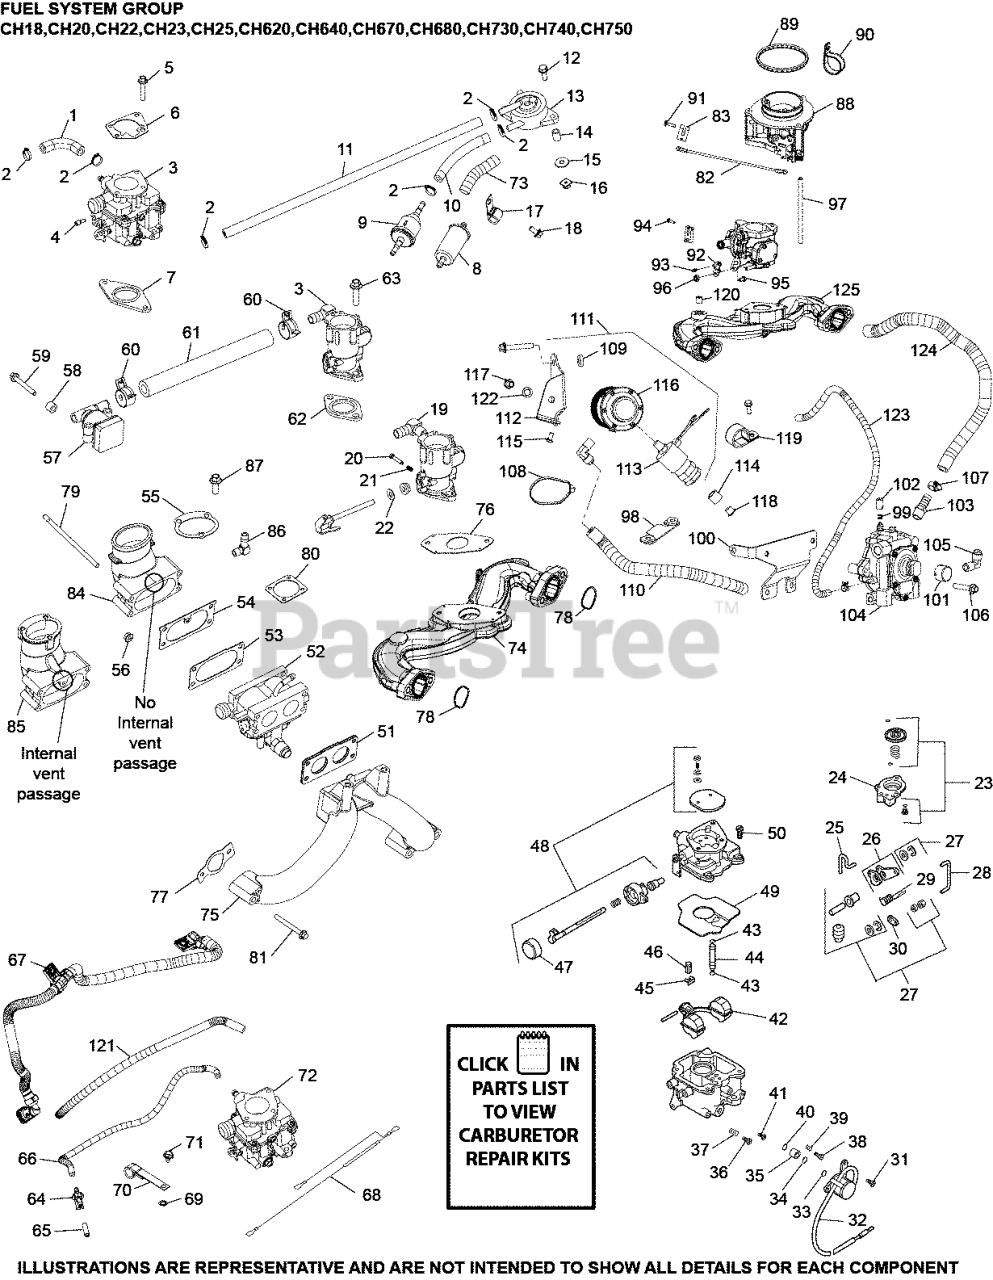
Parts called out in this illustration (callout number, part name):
1	HOSE,LW PERM.FUEL 24.00"-USE 25 111 81-S
2	CLAMP, HOSE (KM)-USE 25 237 31-S
3	KIT,CARB (KEIHIN) W/GASKETS-(#24853310S)
5	SCREW, FLG M6X1.0X25
6	GASKET, AIR CLEANER BASE
7	GASKET, CARBURETOR
9	FILTER, FUEL
18	SCREW, FLG M6X1.0X12
59	SCREW, FLG M6X1.0X40
64	CONNECTOR, EVAPORATIVE
65	CAP, MASKING
66	HOSE, EVAPORATIVE 20" USE 24 326 143-S
68	LEAD, GROUND
69	WASHER, INT TOOTH LOCK 1/4"
74	KIT, INTAKE MANIFOLD
76	GASKET, CARBURETOR
78	O-RING, INTAKE PORT
